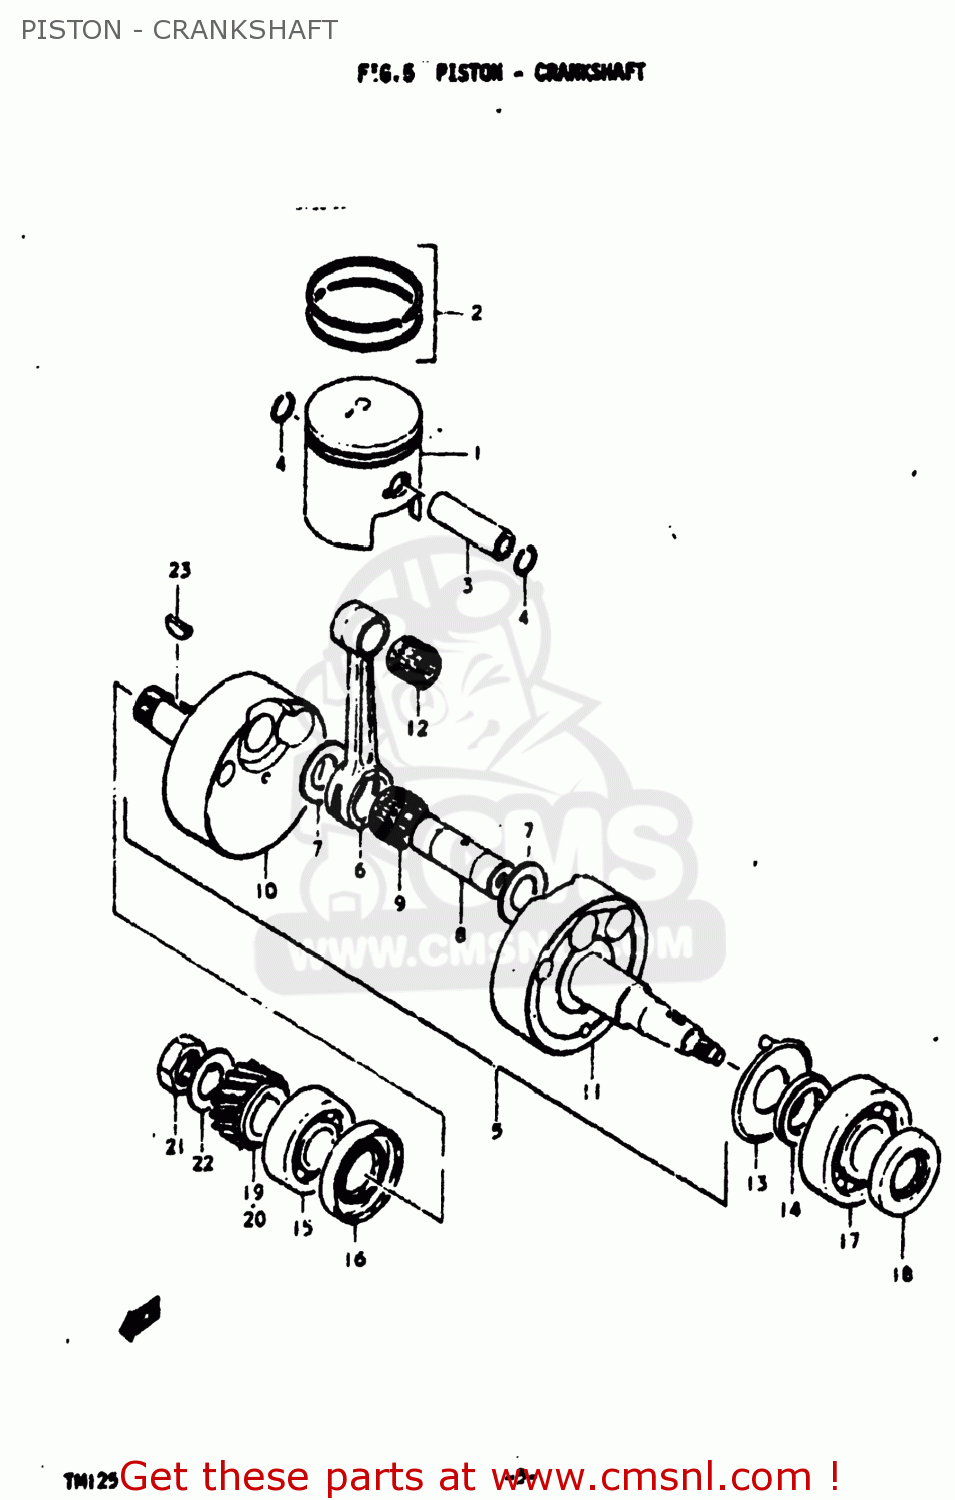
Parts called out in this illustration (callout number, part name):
1	PISTON
2	RING SET,PISTON
3	PIN,PISTON
4	RING,SNAP 14MM
5	CRANKSHAFT ASSEMBLY
6	CONNECTING ROD
7	WASHER
8	PIN,CRANK
9	BEARING
10	CRANKSHAFT
11	CRANKSHAFT,LEFT
12	BEARING
13	PLATE,CRANKSHAFT OIL GUIDE
14	SPACER
15	BEARING
16	SEAL,OIL(26X52X8)
17	BEARING(25X62X17)
18	OIL SEAL
19	GEAR,PRIMARY DRIVE
20	GEAR,PRIMARY DRIVE
21	NUT
22	WASHER
23	KEY
